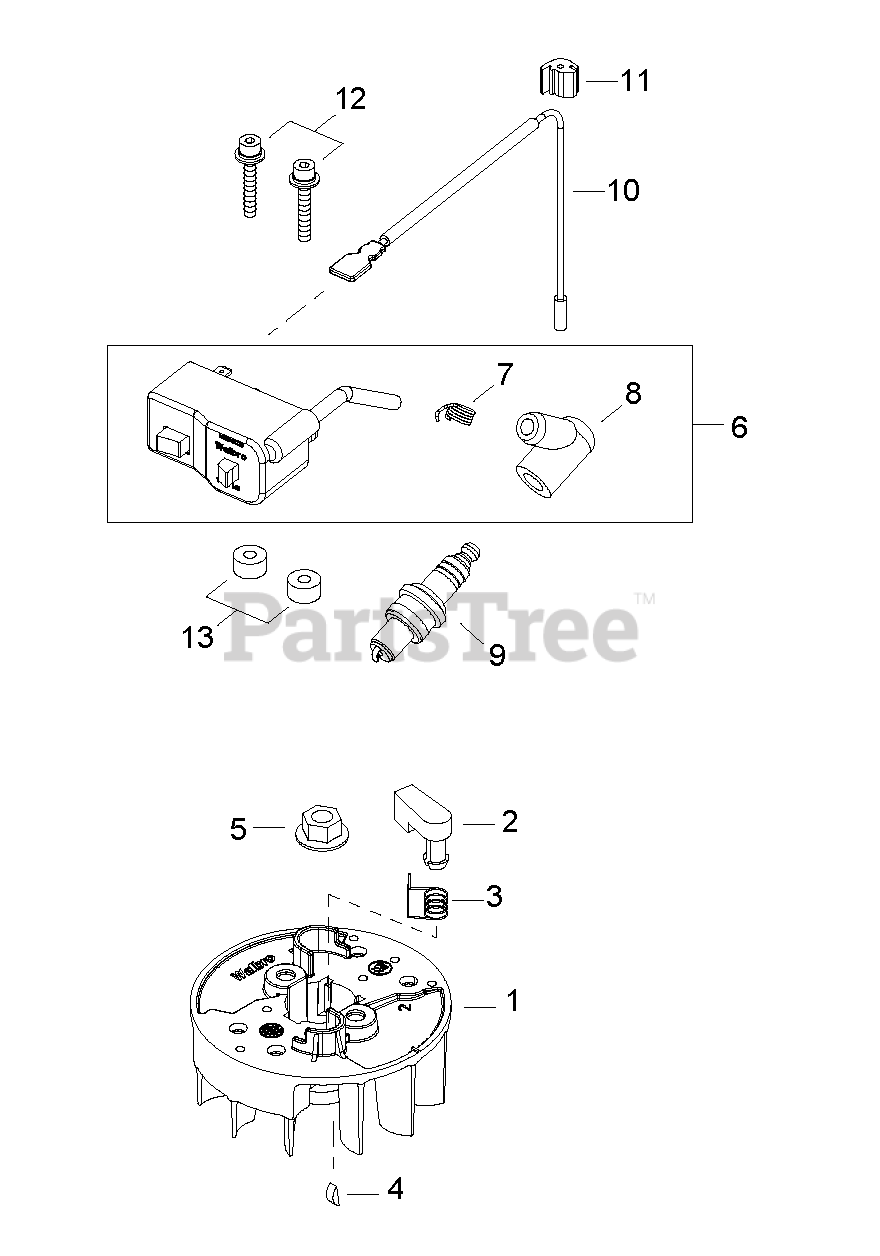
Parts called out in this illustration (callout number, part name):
1	FLYWHEEL
2	PAWL, STARTER
3	SPRING
4	KEY - 3X10
5	NUT - 8
6	IGNITION COIL ASSY
7	TERMINAL, SPARK PLUG CAP
8	CAP, SPARK PLUG
9	SPARK PLUG -- CMR-5H
10	LEAD - IGNITION
11	GROMMET
12	SCREW - 4X26
13	INSULATOR
